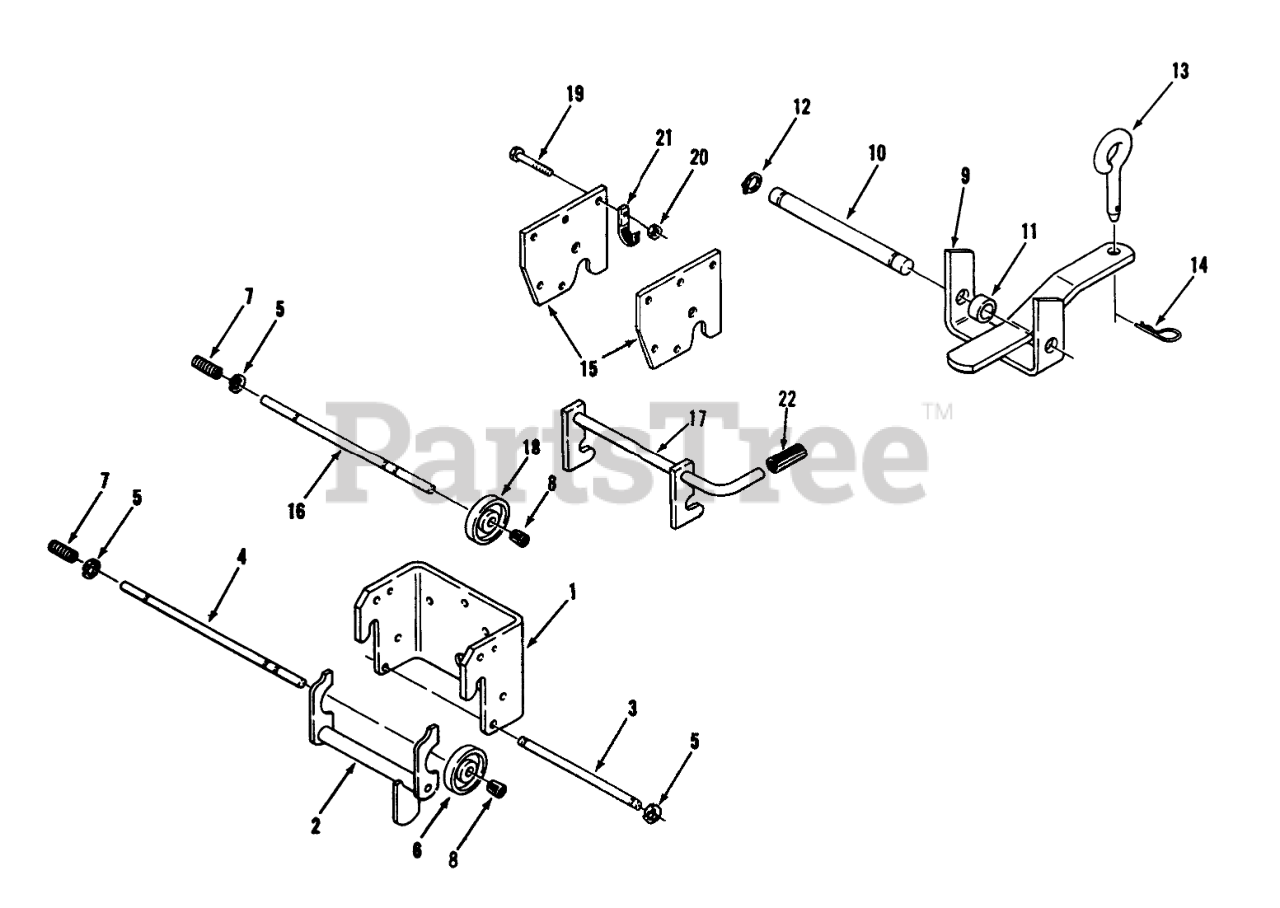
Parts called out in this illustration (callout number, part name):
1	Front Hitch
2	Assy-Latch
3	ROD-LATCH PIVOT
4	ROD-LOCK
5	RING-RETAINING
7	SPRING
8	CAP-ROD, PLUNGER
9	Hitch
10	PIN-STATIONARY HITCH
11	Spacer
12	E-RING
13	PIN-TOOL
14	Hairpin Cotter
15	Hitch Plate
16	ROD-LOCK
17	MID HITCH ASM
19	SCREW-HH
21	CLIP
22	GRIP
